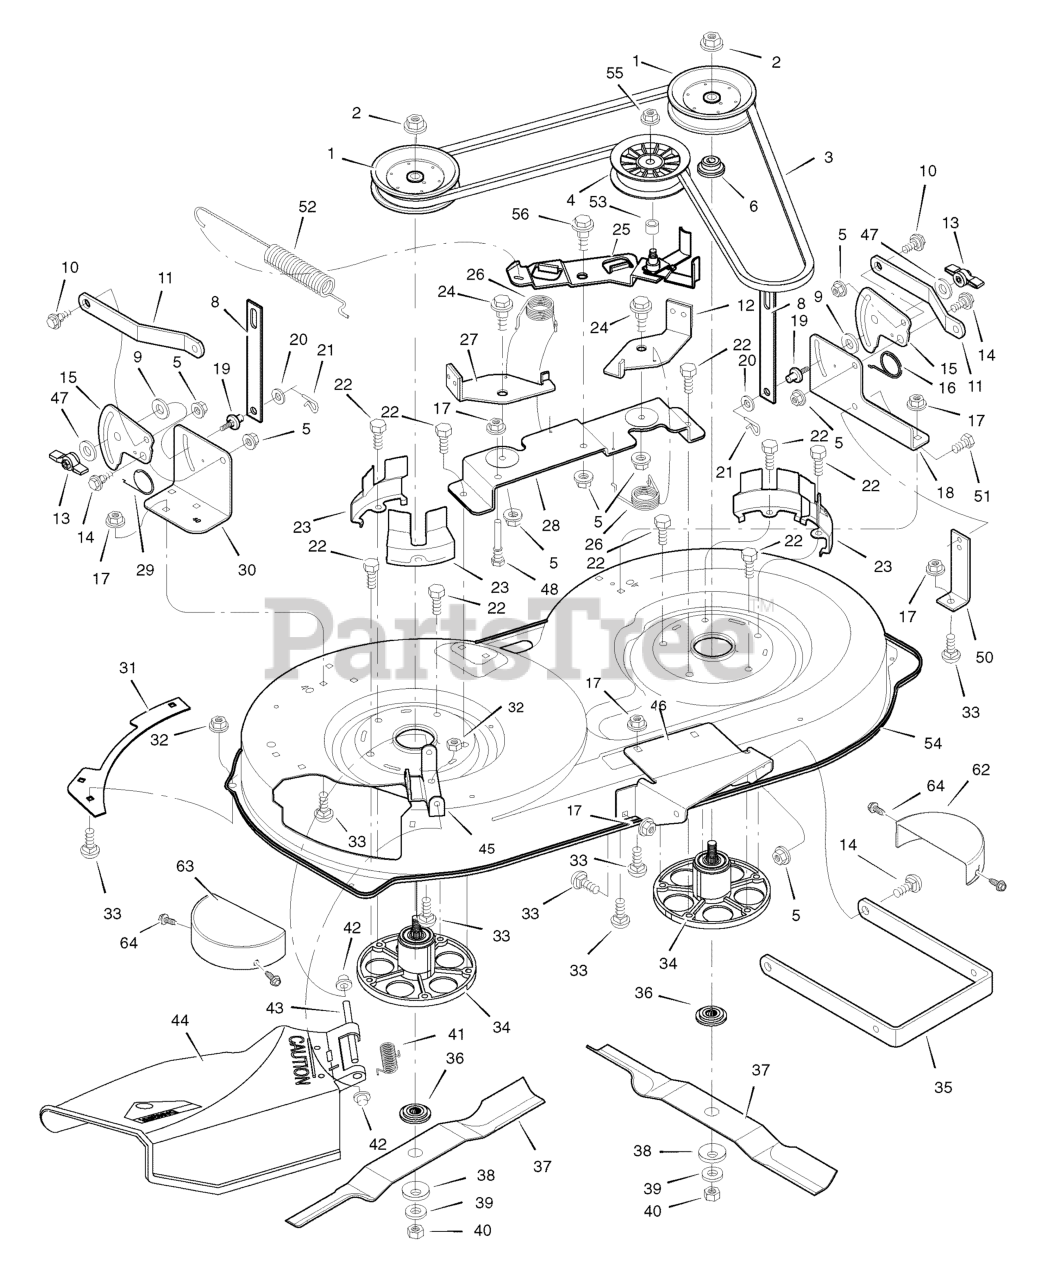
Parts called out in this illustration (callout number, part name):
1	PULLEY Jackshaft
2	NUT, Hex
3	BELT, Mower Drive
4	PULLEY, Idler
5	NUT, Flange
6	Spacer, Pulley
8	LINK, Lift
9	PAD, Friction
10	BOLT, Shoulder
11	BRACKET, Suspension
12	PAD ASSEMBLY, Left Brake
13	KNOB
14	BOLT, Shoulder
15	PLATE, Suspension
17	NUT, Flange
18	BRACKET, Suspension
19	PIN, Hanger
21	PIN, Cotter
23	COVER, Pulley
24	BOLT, Shoulder
25	ARM, Idler
27	PAD ASSEMBLY, Right Brake
28	BRACKET ASSEMBLY, Brake
30	BRACKET, Suspension
32	NUT, Flange
33	BOLT, Carriage
34	MANDRELL
35	BRACKET, Suspension
36	ADAPTER, Blade
42	CAP, Push On
43	ROD, Deflector
44	DEFLECTOR ASSEMBLY
45	BRACKET, Deflector
46	BRACKET, Front Hanger
48	GUIDE, Belt
50	BRACKET, Support
52	SPRING, Extension
54	HOUSING, Blade
55	NUT, Flange
56	BOLT, Shoulder
62	COVER, Pulley L.H.
63	GUARD, Belt R.H.
